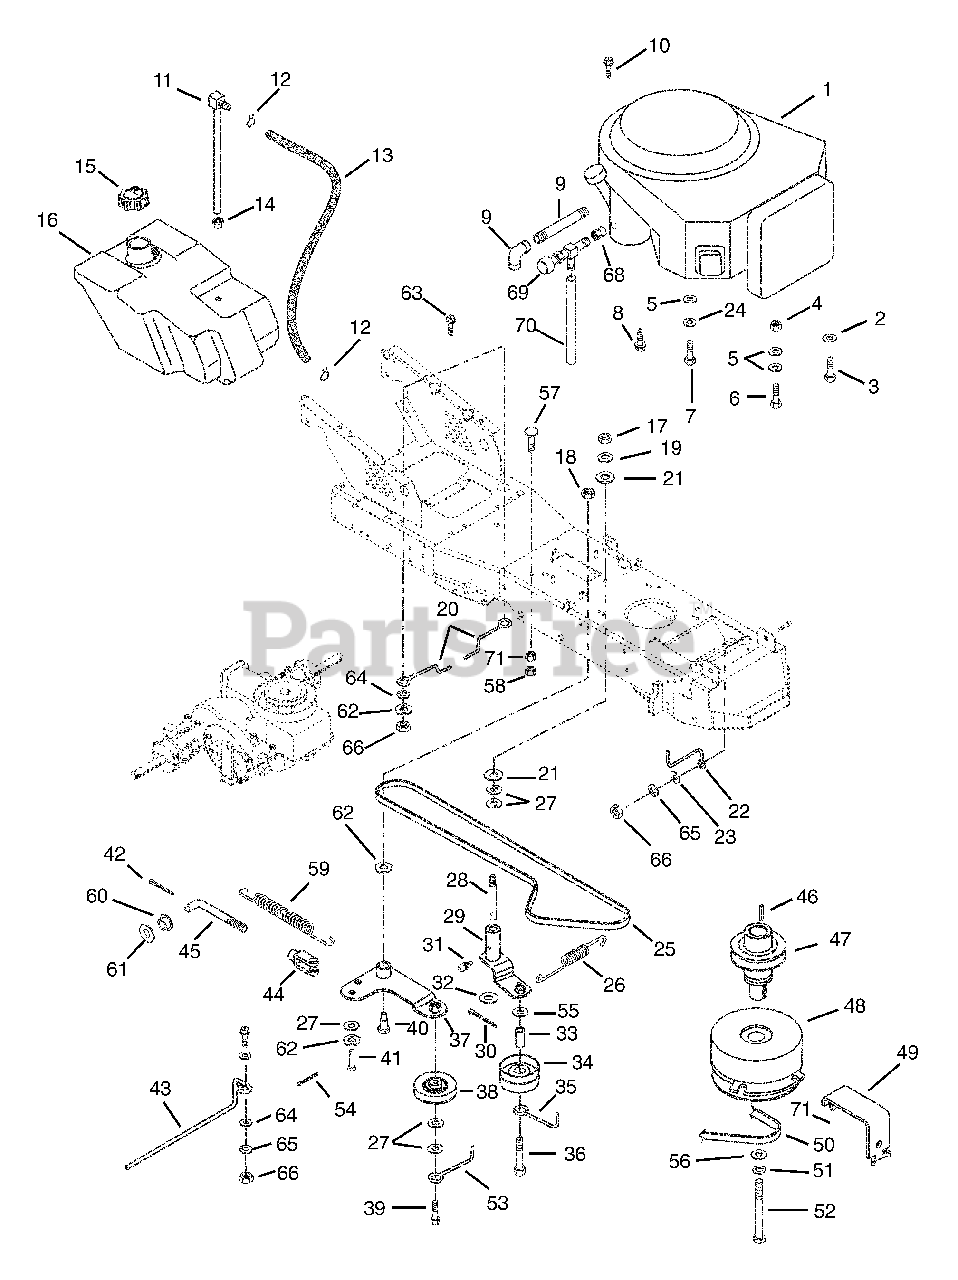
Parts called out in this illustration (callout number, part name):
1	ENGINE BRIGGS 16HP TWIN
1	ENGINE TECUMSEH 13HP VERT
1	BRIGG 15HP W/9AMP CHARGING
1	ENG- 15.0 KOHLER OHV PS-41531
2	@WSHR-LK-EXT.391X.628X.036YWZC
3	@SCR-TAP .38-16X1.25 HWH TR YZ
4	@NUT-LK-CTR .31-18 YWZC
5	WSHR-FL-STL .328X.875X.062YWZC
6	@BLT-HEX .31-18X1.50 GR5 YWZC
7	BLT, HEX M8-1.25X25 GR8.8YWZC
8	NIPPLE
9	ELBOW .375-18 NPTF
10	@SCR-TAP .31-18X.75 HWH TR YWZ
11	TANK FITTING
12	CLAMP-HOSE WIR.490/.510X.092#8
13	HOSE- FUEL LINE 36.00"
13	HOSE- FUEL LINE 48.00"
13	HOSE- FUEL LINE 50.00"
14	BSHG-FLG .375 X 1.062 X .625 R
15	FUEL CAP
16	FUEL TANK
17	@NUT-HEX .38-16 YWZC
18	@NUT-LK-CTR .38-16 YWZC
19	@WSHR-LK .38X.094 REG YWZC
20	BELT FINGER
21	@WSHR-FL-STL.438X1.00X.083 YWZ
22	BELT FINGER
23	@WSHR-FL-STL.312X.734X.065 YWZ
24	@WSHR-LK .31X.078 REG YWZC
25	V-BELT, 4L-WRAPPED
26	SPRING, EXT
27	WSHR-FL-STL .390X.75X.125 YWZC
28	SHOULDER STUD
29	ARM - IDLER PIVOT
30	@PIN-CTR .18X1.25 EXTPRSQCT YZ
31	FTG-LUBE .25-28X.256 YWZC
32	WSHR-FL-STL .52X.827X.062 YWZC
33	TUBE .380 X .625 X 1.620
34	IDLER-FLAT 3.25 X .38 NWHAMSHR
35	FINGER - BELT
36	@BLT-HEX .38-16X3.50 GR5 YWZC
36	@BLT-HEX .38-16X3.75 GR5 YWZC
37	IDLER PIVOT ARM
38	IDLER-V 3X.38
39	@BLT-HEX .38-16X1.75 GR5 YWZC
40	BLT-SHLDR .38-16X1.25
41	PIN-CLEV .312X.822 HDND PL
42	@PIN-CTR .09X.75 EXTPRSQCT YWZ
43	FINGER - BELT
44	YOKE, .312-24 X 2.25
46	KEY-SQ .25 X 1.25 X .25 SAE
47	SHEAVE EXTENSION SHAFT-GEAR
47	SHEAVE EXTENSION SHAFT- HYDRO
48	ELECTRIC CLUTCH/BRAKE (3.4AMP)
48	CLUTCH, ELECTRIC - WARNER
49	ANCHOR - CLUTCH
50	V-BELT, 4L-RAW EDGE
51	WSHR-LK .438X.133 HVY YWZC
52	BLT-HEX .44-20X4.00 GR5 YWZC
52	BLT-HEX .44-20X4.50 GR8 YWZC
53	FINGER - BELT
54	PIN-HAIR INT .08X.18X1.18 YWZC
55	WSHR-FL-STL .390X.88X.18 YWZC
56	WSHR-FL-STL.463X1.375X.25 YWZC
57	BLT-RDHDSQNK .31-18X1.0 SHTYZ
58	@NUT-LK-CTR .31-18 YWZC
59	SG-TENS .105X.85X5.00 WLD 40
60	BSHG-FLG .320X.620X.312 NY
61	WSHR-FL-STL .505X.880X.072 YWZ
62	WAVE WASHER .531X.781X.125FH
63	BLT-RDHDSQSHK.31-18X.75 GR2 YW
64	@WSHR-FL-STL.344X.688X.065YWZC
65	WSHR-LK .312X.097 HVY YWZC
66	@NUT-HEX .31-18 YWZC
67	J-CLAMP
68	ADAPTER, OIL DRAIN
69	COCK, OIL DRAIN
70	TUBE OIL DRAIN
71	NUT-LK-NYL.312-18 PL
